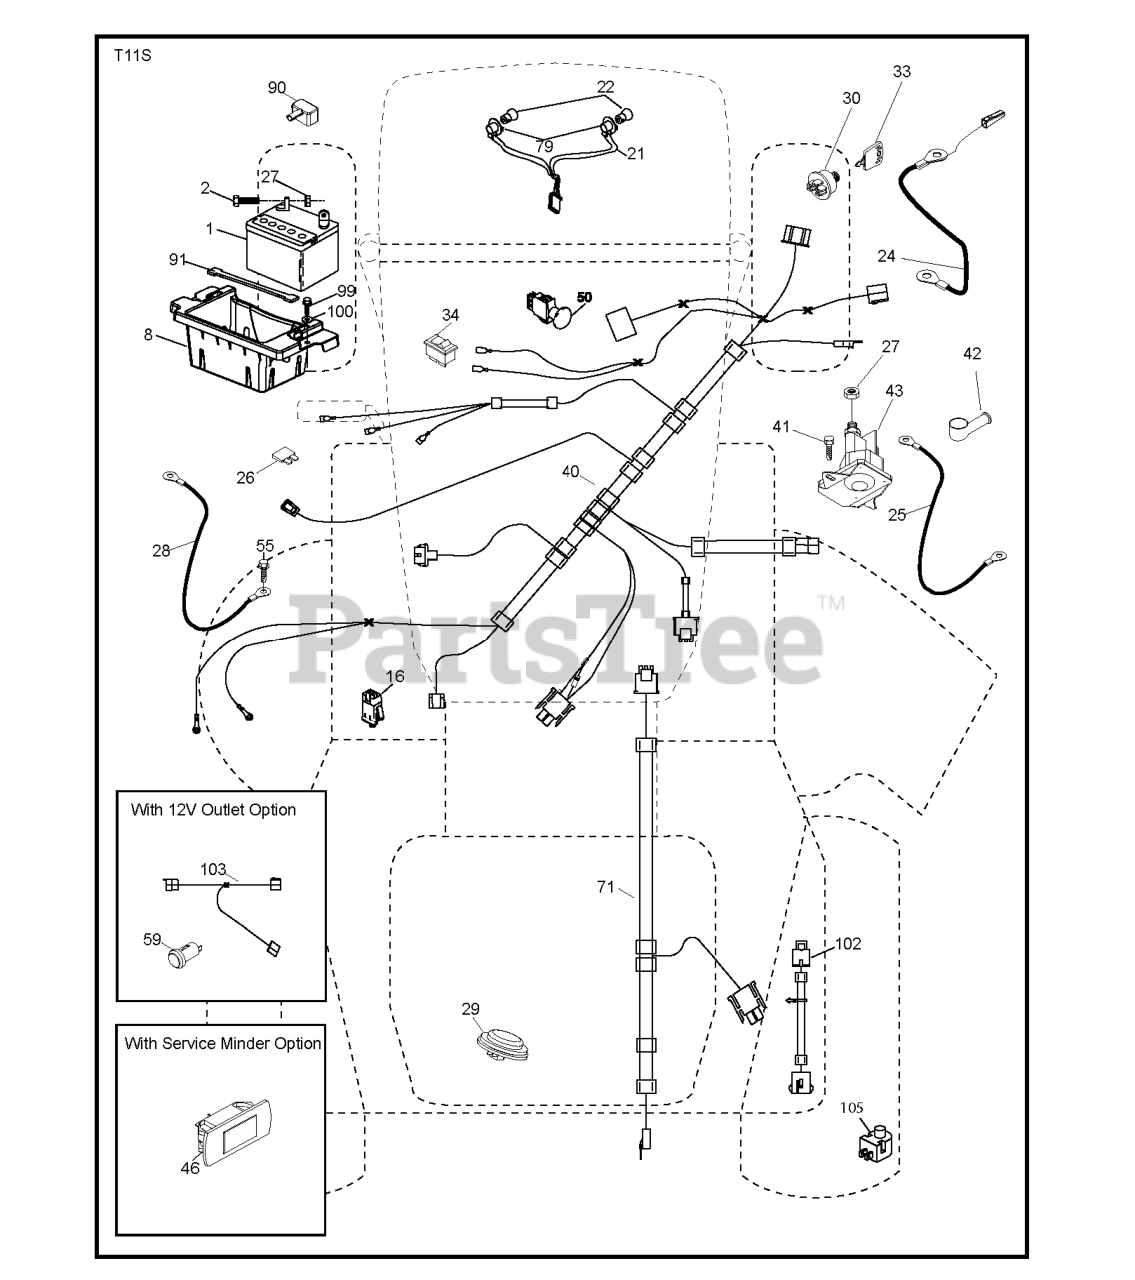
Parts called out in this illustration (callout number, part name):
1	Battery 12 Volt 25 Amp
2	BOLT.HEX.1/4.X.3/4.DICHROMATE
8	BOX.BATTERY.MOUNT.FRONT.LT
16	SWITCH INTERLOOK PUSH-IN
21	HARNESS ASSY LIGHT
24	CABLE.BATT.POS.WIRE.TG.DA SOL
25	CABLE.STARTER.6G.BL/RED.17.5
26	FUSE 20AMP
27	NUT
28	CABLE GROUND 6 GA 21" 90T BLK
29	SWITCH.SEAT.DELTA.OPC.
30	SWITCH.IGN.DELTA.W.LGH.ROS
33	KEY.CHAIN.BLISTER.PACK.GEN.USA
40	HARNESS.IGN.DASH.HUQ/P
41	SCREW
42	TERMINAL COVER
43	SOLENOID.W/BRASS.PLUNGER
46	RP.GUAGE.SRVCMNDR.HRMTR.
50	RP.PTO.SWITCH.8 TERMINAL.BLACK
55	SCREW 5/16"
71	HARNESS-CHASSIS SUB
79	BULB HOLDER ASM.
90	COVER.TERMINAL.BATTERY
91	STRAP.BATTERY.MOUNT.FRONT(2 2)
99	SCREW HEXWSHR 1/4-20X3/4
100	WASHER
102	HARNESS PIGTAIL PCH TEX ROS
105	REVERSE SWITCH
